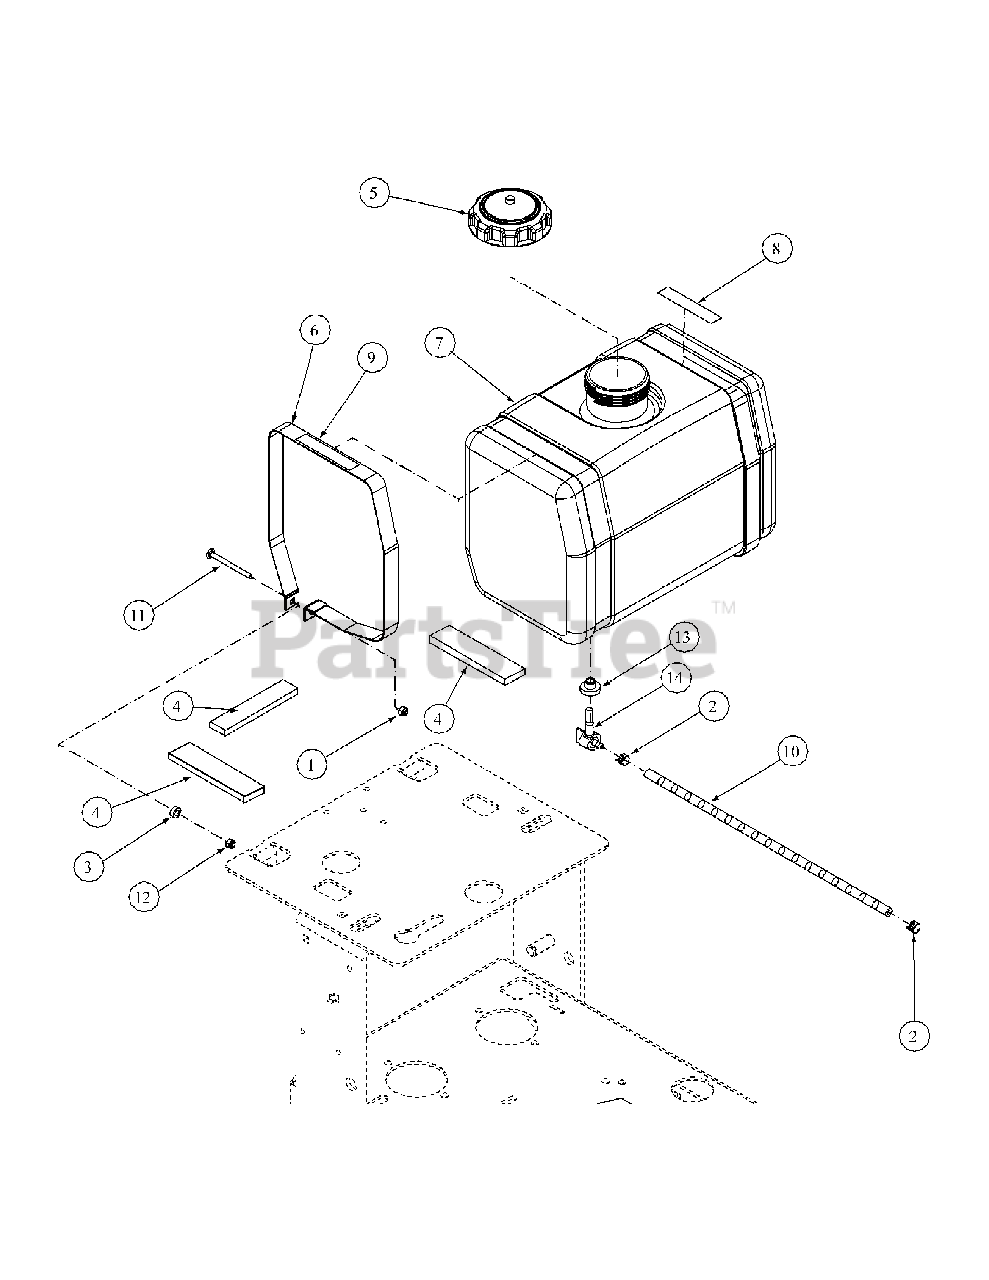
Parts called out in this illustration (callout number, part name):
1	Lock Nut, Nylon Insert, 1/4-20
2	Uni-Clamp
4	Stop Pad, Rubber
5	Fuel Cap, 3.5
6	Fuel Tank Strap
7	Fuel Tank
8	Mower Warning Label, Turn off Engine
9	Mower Instruction Label, Fuel Valve
10	18" Hose
11	Carriage Bolt, 1/4-20 x 3.00
12	Nut, 1/4-20
13	Grommet Fuel Tank
14	Shutoff Valve
